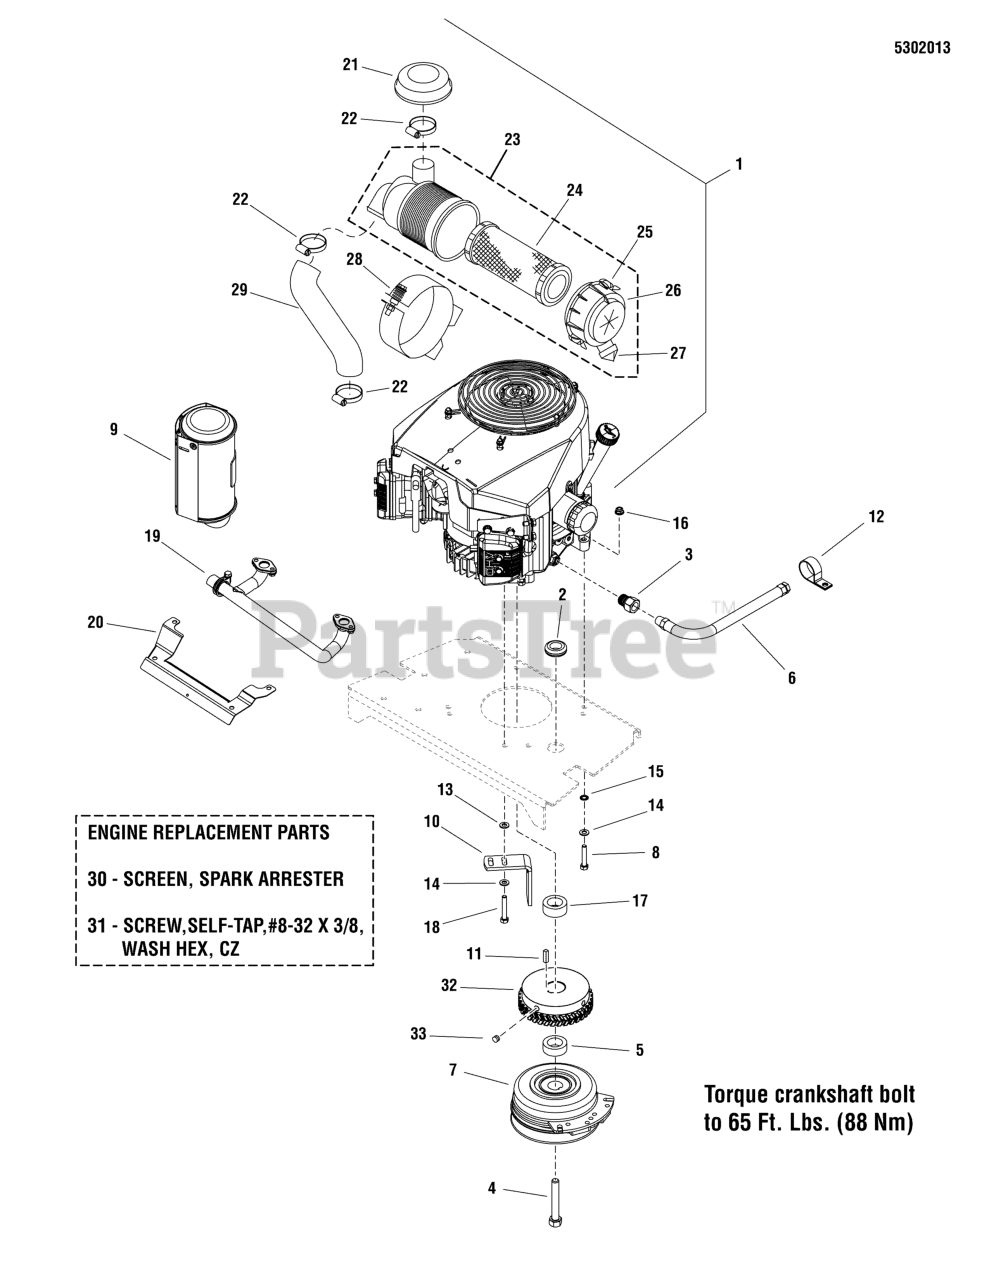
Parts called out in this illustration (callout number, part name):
1	ENGINE, 19HP, KAWASAKI
2	GROMMET, 7/8
3	ADAPTER-OIL DRAIN
4	BOLT, CRANKSHAFT, 7/16 X 2-1/2
5	SPACER, 1.13 X 1.75 X .62
6	HOSE, OIL DRAIN
7	* CLUTCH, 5218-134, WARNER
8	BOLT, 5/16-18 X 1-3/4 GD5 YZ
9	MUFFLER, FUEL PUMP SIDE, 19HP KAWI
10	ANCHOR, CLUTCH - BLK
11	KEY, 1/4 SQ X 1
12	CLAMP, VINYL COATED, 5/8 ID
13	WASHER, 5/16 USS
14	WASHER, 5/16" SAE
15	WASHER, 5/16 INT. TOOTH LOCK
16	NUT, 5/16-18 HEX NYLOCK FLANGE
17	SPACER, 1.13 X 1.75 X .75
18	BOLT, 5/16-18 X 2, GD5
19	MANIFOLD. EXHAUST
20	HEAT SHIELD, EXHAUST MANIFOLD
21	RAIN COVER
23	AIR FILTER ASSEMBLY (REF NO. 24 - 27)
24	AIR FILTER, ELEMENT
25	CLAMP, CAP
26	CAP, FILTER CASE
27	RUBBER DUST CAP
28	CASE, BRACKET, COMPLETE
29	AIR INLET TUBE
32	SPROCKET, 44T X 1.125 BORE, EAGLE PD
33	SET SCREW, 5/16-18 X 3/8 PCH.
